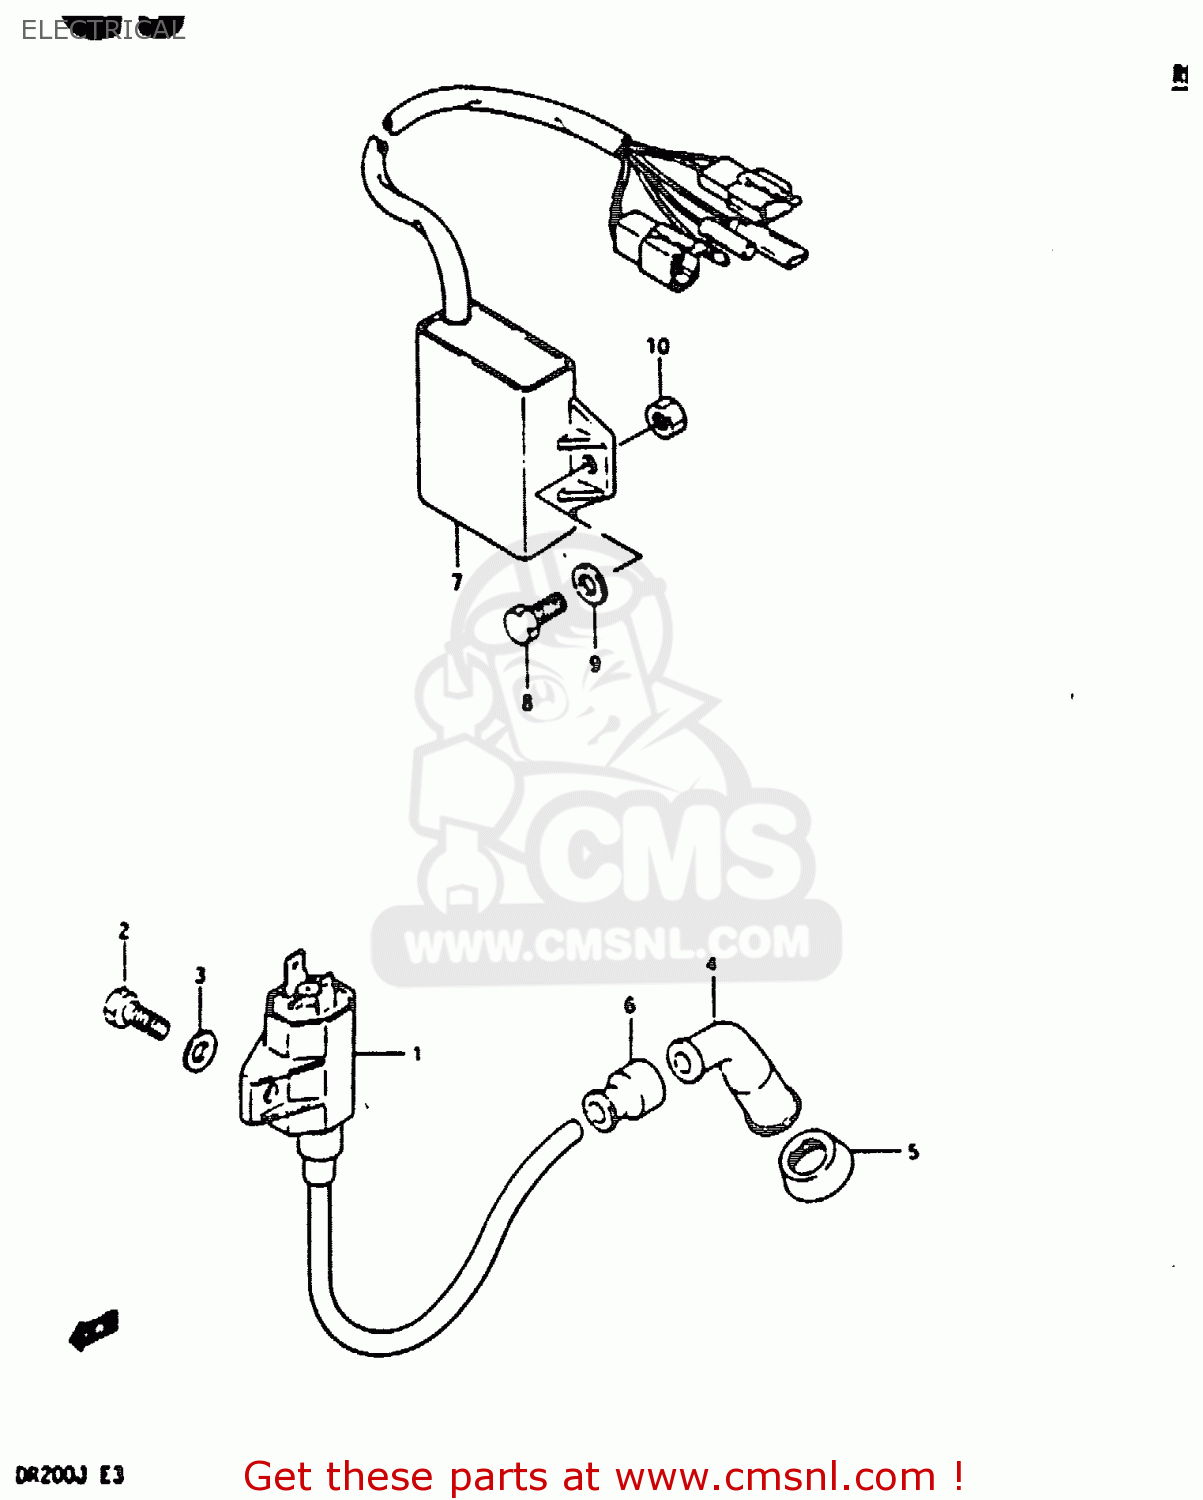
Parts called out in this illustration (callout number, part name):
1	COIL ASSEMBLY,IGNITION
2	BOLT
3	WASHER, LOWER
4	CAP,SPARK PLUG
5	SEAL,SPARK PLUG CAP
6	SEAL,SPARK PLU
7	CDI UNIT
8	BOLT
9	WASHER, LOWER
10	NUT
